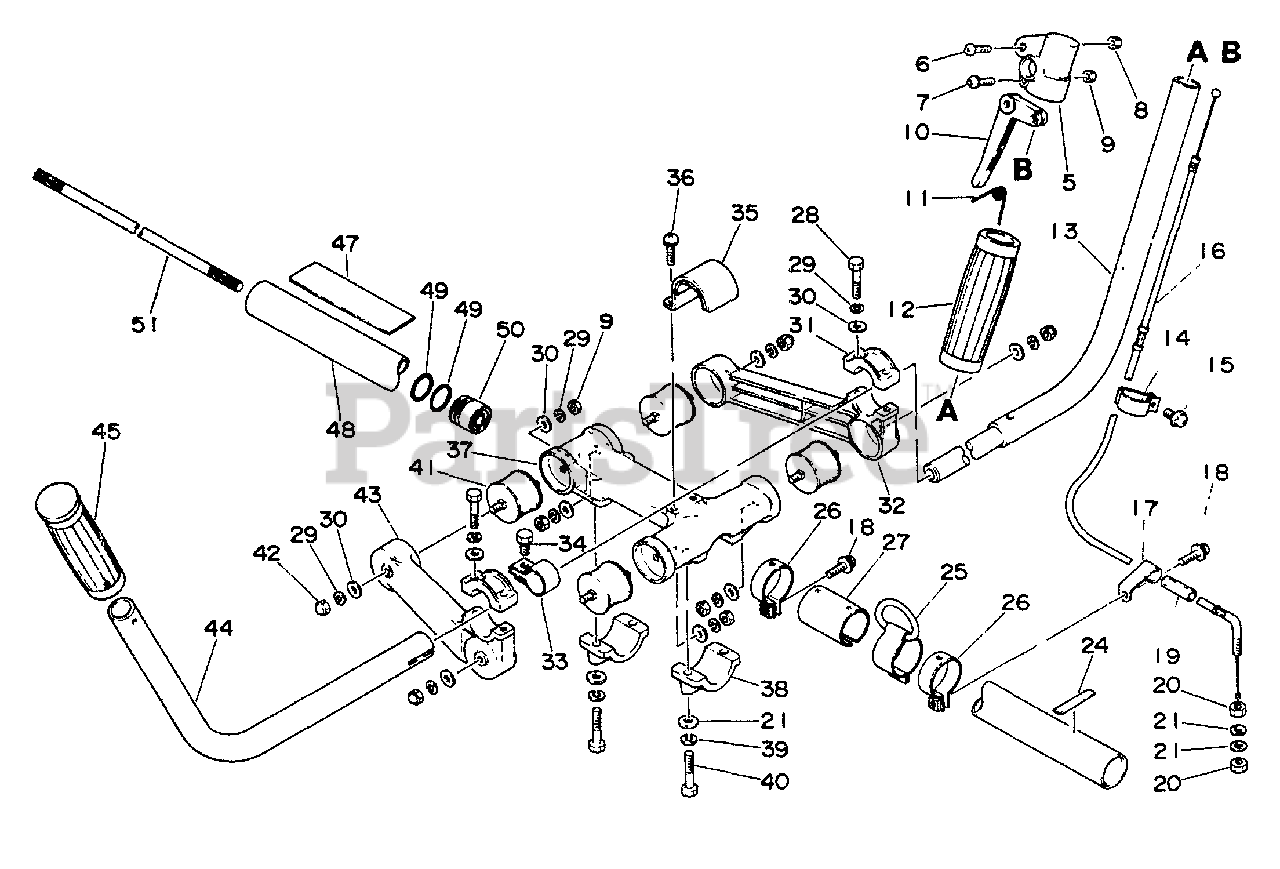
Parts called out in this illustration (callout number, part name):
5	BRACKET, TRIGGER
6	SCREW - 5X30
7	SCREW - 5X25
8	LOCKNUT - 5
10	TRIGGER, THROTTLE
11	SPRING, TRIGGER
12	GRIP, HANDLE
14	CLAMP
15	SCREW - 5X12
16	CABLE, THROTTLE
18	SCREW - 5X14
21	WASHER - 6
24	LABEL - ALIGNMENT
25	HOOK
26	HOOK
27	COLLAR
28	BOLT - 5X25
29	LOCKWASHER - 5
30	WASHER - 5
31	RETAINER
32	ARM, RETAINER - RIGHT
33	CLAMP
34	SCREW - 6X12
35	PLATE
36	SCREW - 5X14
37	Holder, d.s. housing
38	HOLDER
39	LOCKWASHER - 6
40	BOLT - 6X30
41	CUSHION
42	NUT - 5 -- CAP
43	ARM, HANDLE - LEFT
44	HANDLE
45	GRIP, HANDLE - LEFT
47	LABEL - CAUTION
48	MAIN PIPE ASSY
50	STOPPER
51	DRIVESHAFT - SOLID
